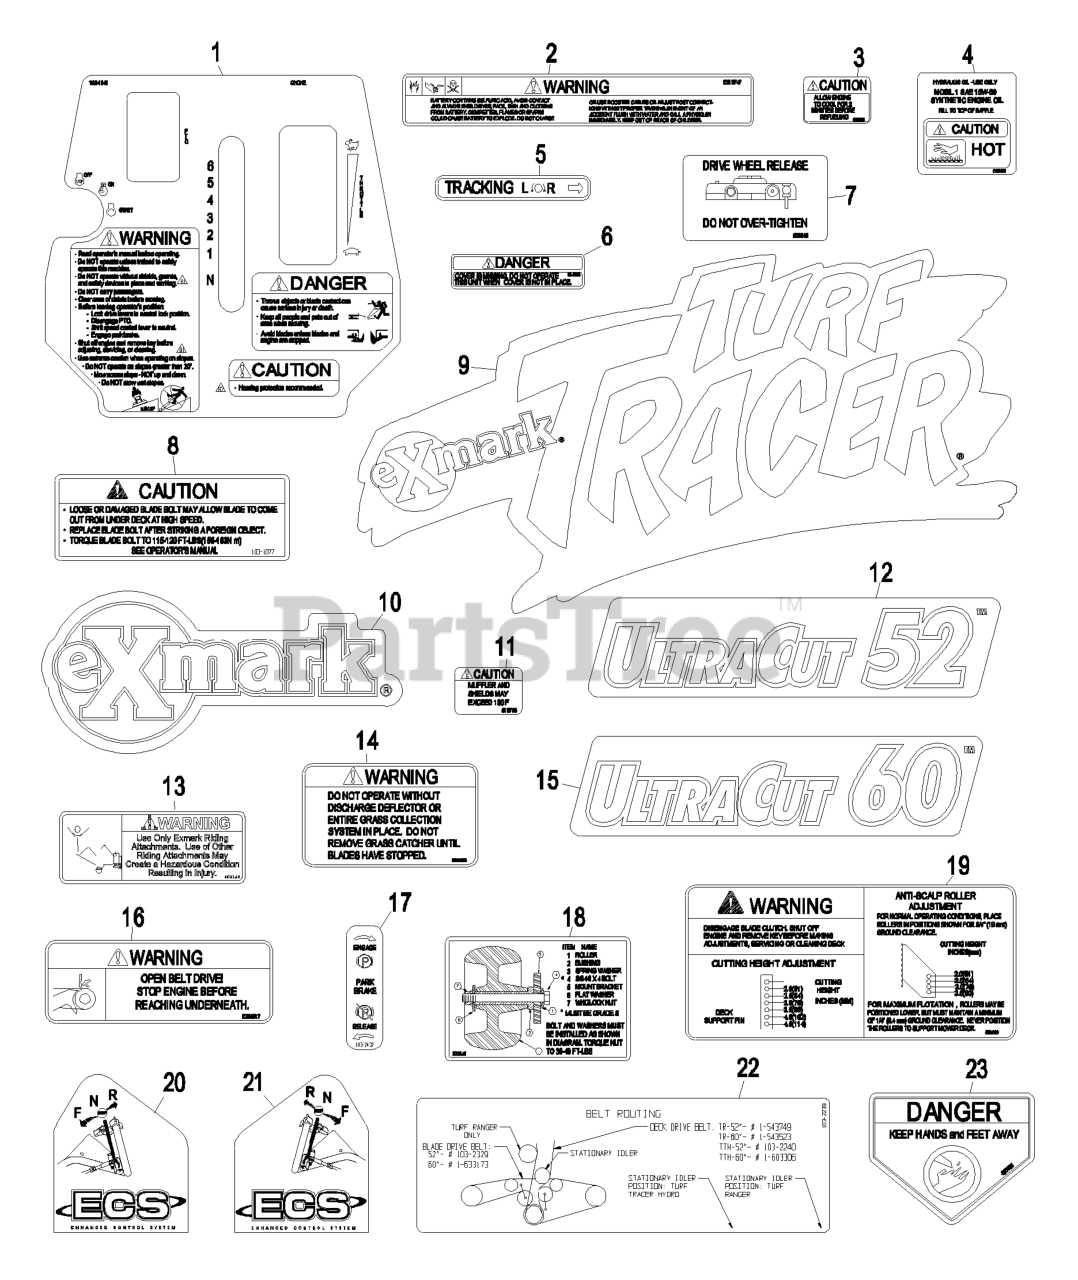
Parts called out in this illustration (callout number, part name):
1	DECAL,TTH ECS CONSOLE
2	DECAL-BATTERY
5	DECAL,TRACKING ADJUST
6	DECAL-COVER, MISSING
7	DECAL,DRIVE RELEASE
8	DECAL,BOLT TORQUE
9	DECAL,TTH "SWASH"
12	DECAL,ULTRACUT 52
13	DECAL,SULKY WARNING
14	DECAL-WARNING, DISCHARGE
15	DECAL,ULTRACUT 60
16	DECAL,BELT DRIVE
17	DECAL,PARKING BRAKE
18	DECAL,ROLLER MOUNTING
19	DECAL,ANTI SCALP
20	DECAL,LH ECS INSTRUCTION
21	DECAL,RH ECS INSTRUCTION
22	DECAL,BELT ROUTING
23	DECAL-DANGER
